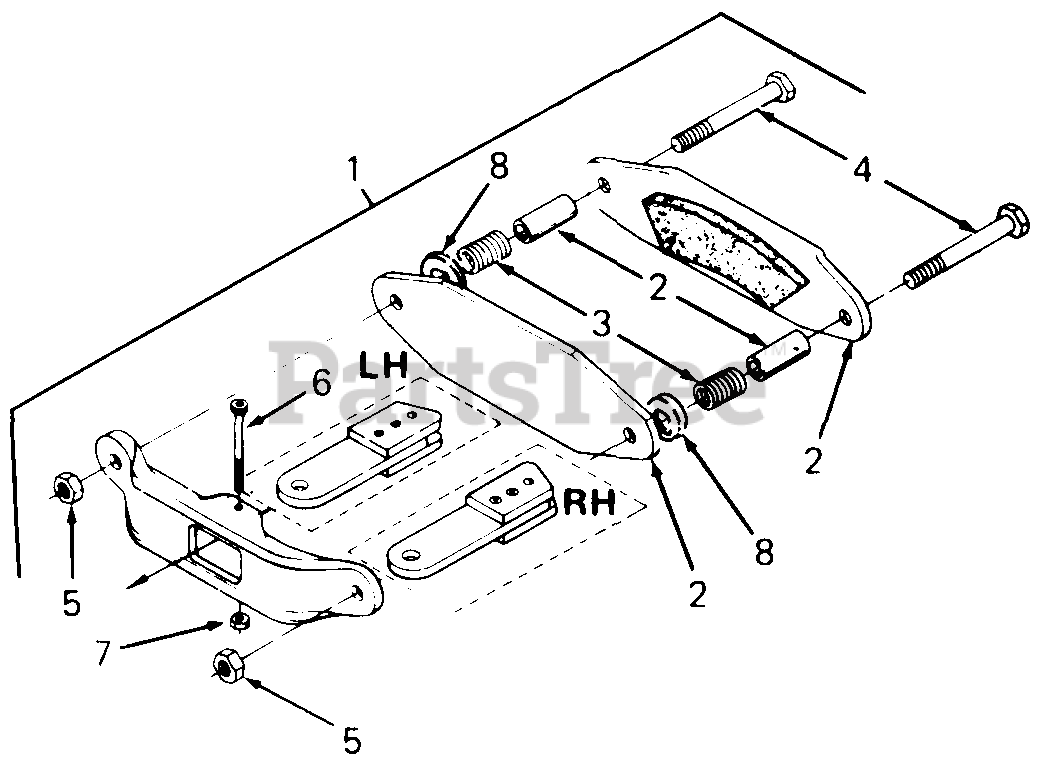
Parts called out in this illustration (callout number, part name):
1	Kit, Brake Caliper
2	Puck Kit, Brake
3	Spring, Compression
4	Screw, Hex Cap, 3/8-24 x 2.25 Lg
5	Nut, Hex Lock, 3/8-24 GR5
6	Screw, Socket Hd Shld, 1/4-20 x 1.25 Lg
7	Nut, Hex Top Lock Jam, 1/4-20 GR5
8	Washer, Flat, .390 x 1.0 x .030 Thk HDN
